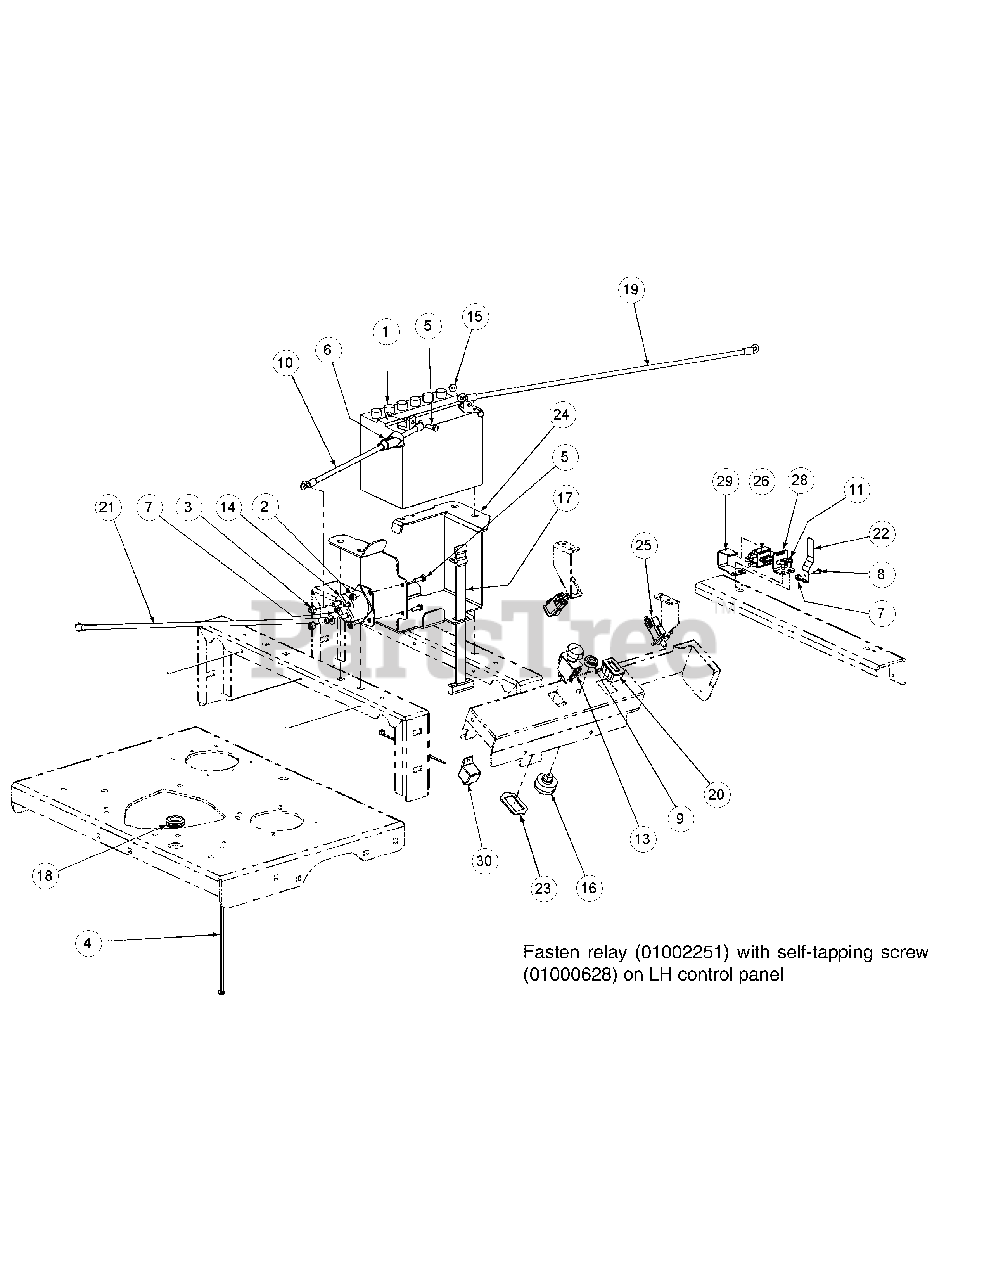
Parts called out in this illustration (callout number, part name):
1	Battery, 12V 225CCA 30 Min
2	Lock Nut w/Nylon Insert
3	Nylock Nut, 5/16-18
4	Tie, Cable, 3/16 x .05 x 7.4"
5	Screw, Hex, Cap, 1/4-20 x .75
6	Boot, 1" OD Rubber Battery-PST, Red
7	Nut, Lock, Nylon Insert, #10-32
8	Screw, Hex Washer, 10-32 x 1/2
9	Nut, W/Cap, 5/8-32 Ignition
10	Cable, Battery, Red, 15"
11	Screw, TT, 1/4-20, 0.5, Hex Index Washer
13	Switch, Electric, PTO
14	Solenoid Magnetic Switch
15	Hex Flange Lock Nut, 1/4-20
16	Switch, Ignition, 6 Pin
17	Strap, Battery
18	Grommet, .75 ID
19	Cable, Battery Black, 28"
20	Meter, Hour
21	Cable, Battery Red, 32"
22	Spring Retainer
23	Bracket, PTO Switch Retainer
24	Mount Bracket, Battery
25	Switch, Safety N.O./N.C.
26	Switch, Plunger
28	Bracket, Plunger Switch
29	Clamp, Plunger Switch
30	Relay, 12V 40A
